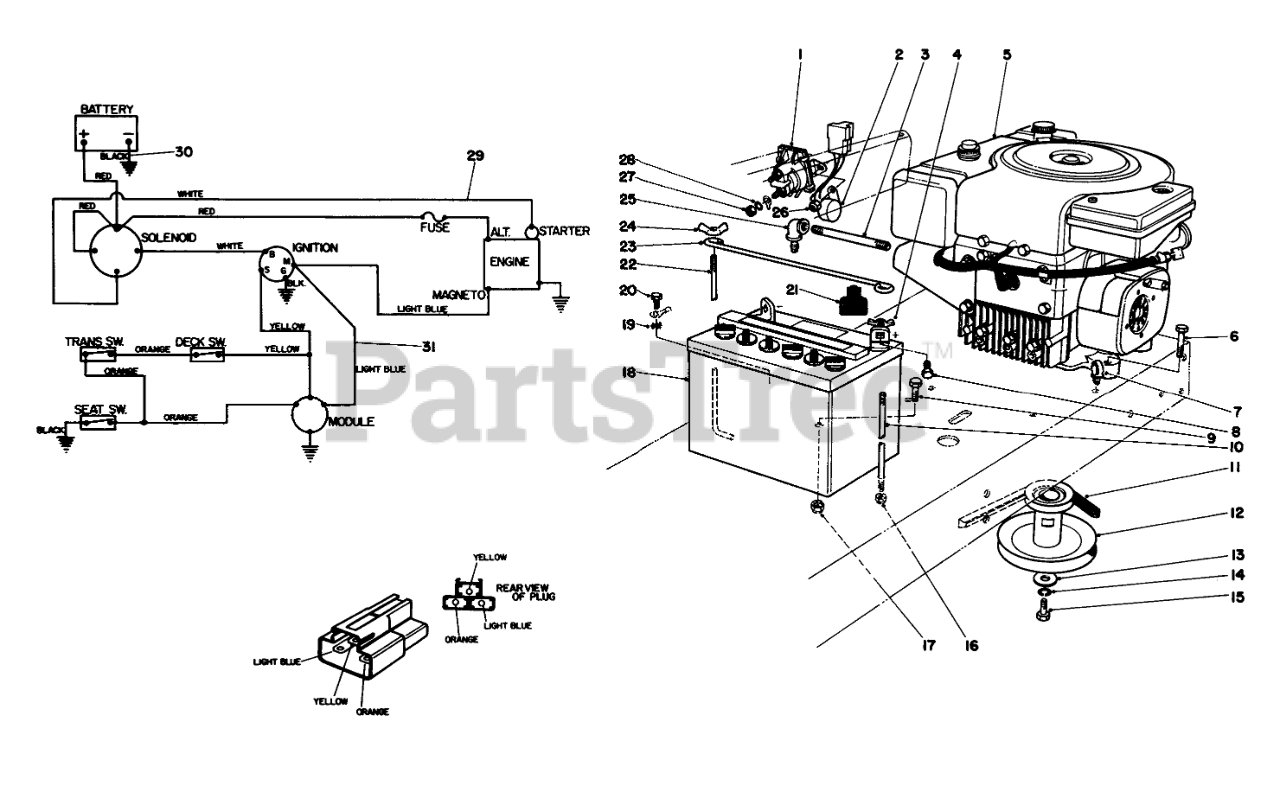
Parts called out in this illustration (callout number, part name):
1	SOLENOID
2	Module Interlock
3	NIPPLE
4	NUT-WING
5	Engine
6	SCREW-HH
7	Clip-Cable
8	SCREW-HH
9	SCREW-HH
10	BATTERY BOLT
11	V-BELT, TRACTION
12	PULLEY
13	WASHER
14	WASHER-LOCK
15	SCREW-HH
16	NUT-KEPS
17	NUT-LOCK, CONE
18	Battery
19	WASHER-LOCK, INTERNAL
20	SCREW-HHF
21	BOOT-TERMINAL
22	ROD-SUPPORT, BATTERY
23	BATTERY HOLD DOWN
24	NUT-WING
25	ELBOW-90 DEGEE
26	NUT-LOCK, CONE
27	NUT-JAM
28	WASHER-LOCK
29	Wiring Harness
30	Wire-Battery to Ground
31	Wiring Harness
